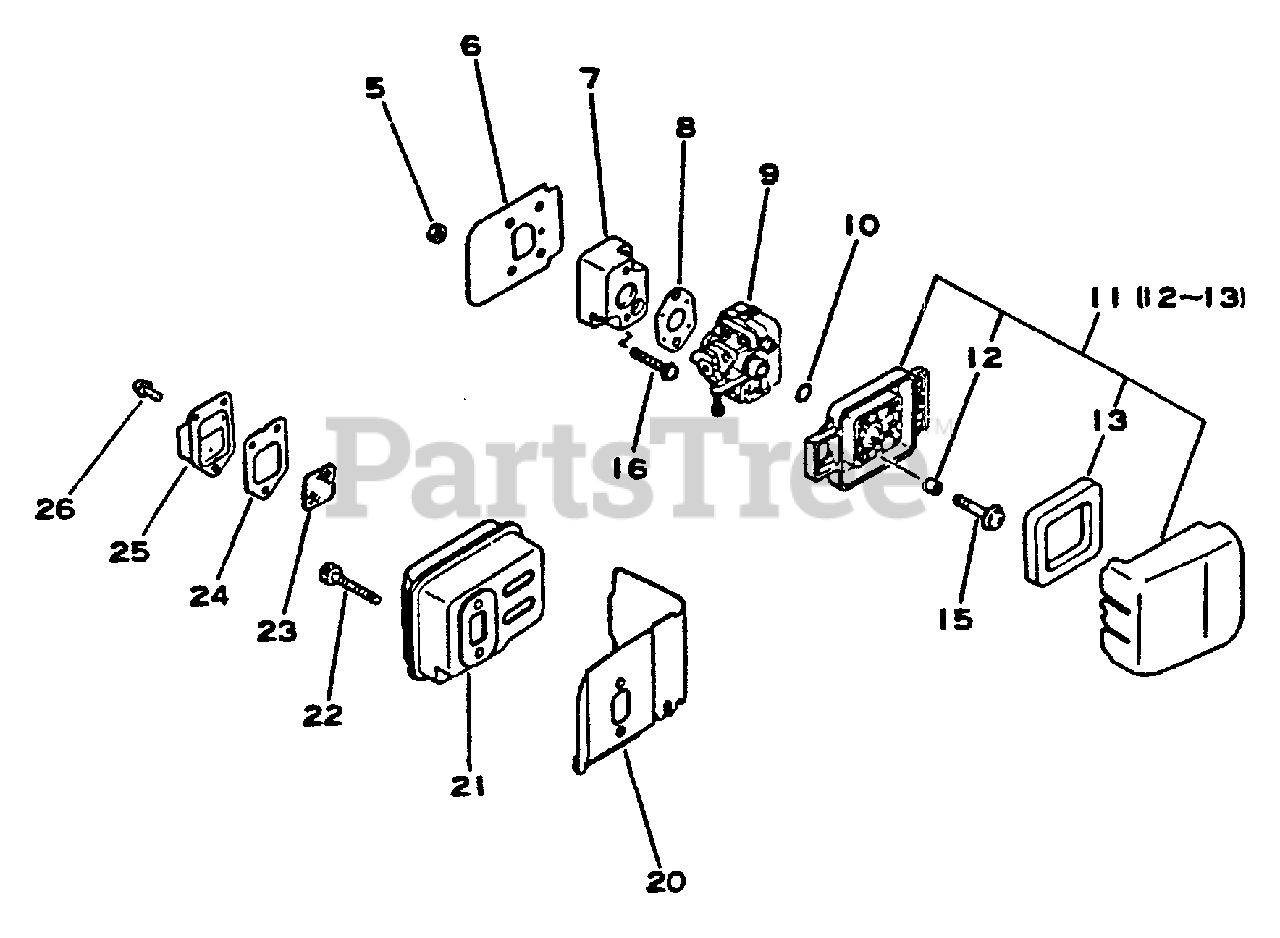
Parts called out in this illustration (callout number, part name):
5	NUT M5
6	HEAT SHIELD, INTAKE
7	INSULATOR, INTAKE
8	GASKET, INTAKE
9	CARBURETOR
10	O-RING 15
11	AIR FILTER ASSY
12	SLEEVE
13	FILTER, AIR
15	SCREW 5×64
16	SCREW 5×20
20	GASKET, EXHAUST
21	MUFFLER
22	BOLT 5×55
23	SCREEN, SPARK ARRESTER
24	GASKET, EXHAUST
25	LID, MUFFLER
26	SCREW - 4×10
